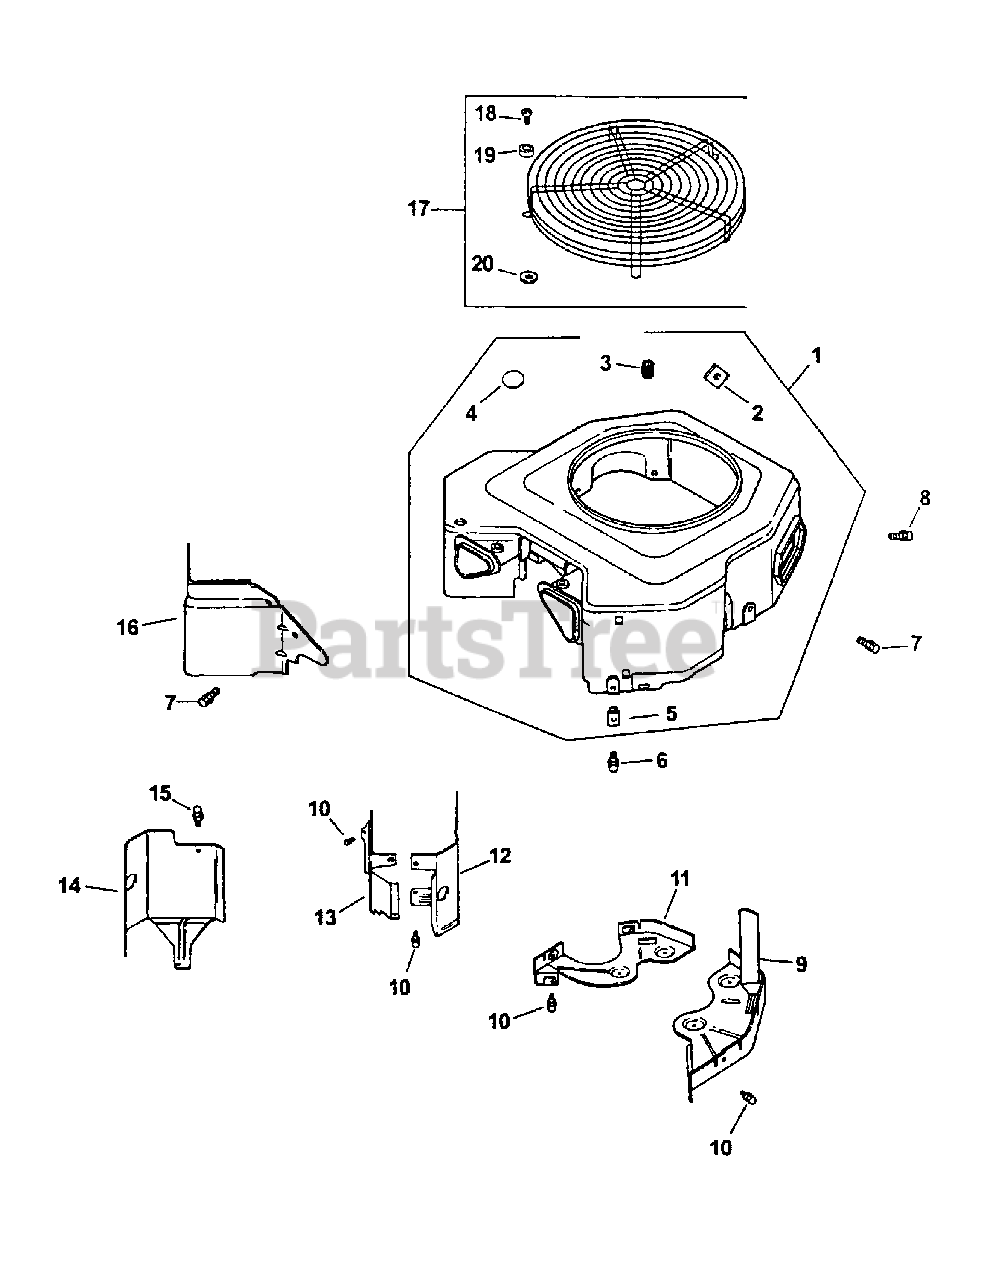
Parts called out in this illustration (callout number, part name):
1	Housing, Blower
2	Nut, Plastic
3	Screw, Set
4	Plug, Button 9/16"
5	Nut, Plastic
6	Screw, Hex Flange
7	Screw, Hex Flange
8	Screw, Hex Flange
9	Plate, Backing - #2 Side
10	Screw, Hex Flange
11	Plate, Backing - 01 Side
12	Baffle, Cylinder Barrel - #2 Side
13	Baffle, Valley - #1 Side
14	Baffle, Cylinder Barrel - #1 Side
15	Screw, Hex Flange
16	Baffle, Valley - #2 Side
17	Kit, Fixed Guard
18	Screw, Pan Head
19	Spacer
20	Washer, Plain 1/4"
